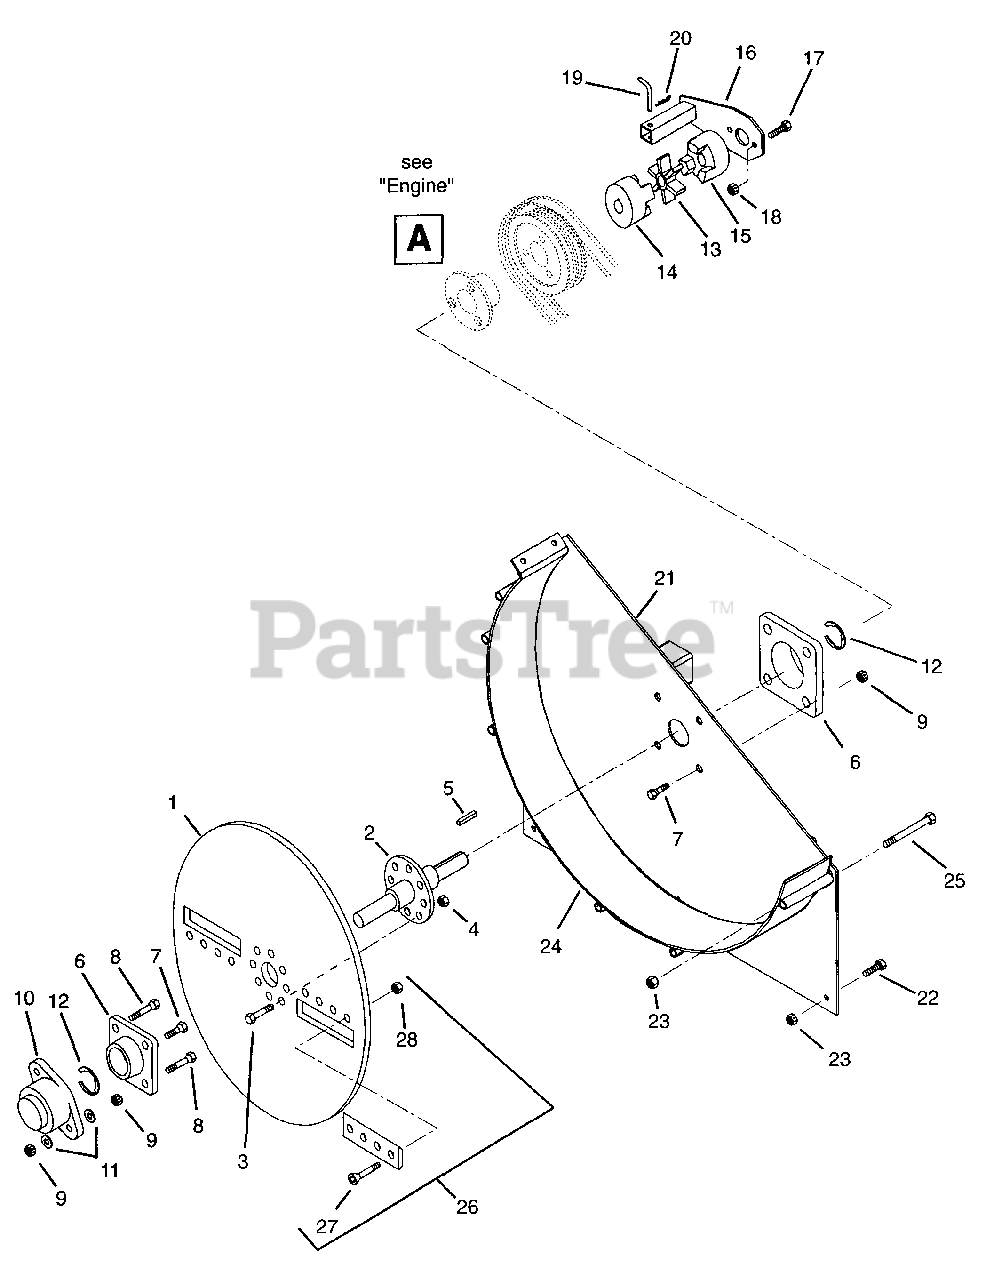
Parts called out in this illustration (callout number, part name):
1	Cutting Wheel
2	Arbor Shaft
3	Bolt-Hex .50-13 x 2.00 Grade 5
4	Nut-Locking-Center .50-13
5	Key-Straight .38 x 2.75 x .38
6	4 Hole Flange Bearing
7	Bolt-Lug .50-20 x 1.50
8	Wheel Lug Bolt 1/2-20 x 2.50
9	Nut-Locking-Center .50-20
10	Bearing Cover
11	Washer-Flat-Steel .531 x 1.06 x .095
12	Ring-Retaining-External 1.500 x .109
13	Flex Joint Coupler
14	Coupler Half
15	Coupler Half
16	Hydraulic Pump Mount
17	Bolt-Hex .44-14 x 1.50 Grade 5
18	Nut-Locking-Center .44-14
20	Pin-Hair-Internal
21	Plate Weldment-Flywheel Housing
22	Bolt-Hex .38-16 x .75 Grade 5
23	Nut-Locking-Center .38-16
24	Wrapper Weldment-Flywheel Housing
25	Bolt-Hex .38-1 6 x 5.75 Grade 5
26	Chipper Knife Set
27	Bolt-Flat Socket Head .50-13 x 1.75 Grade 8
28	Nut-Locking .50-13 Grade C
